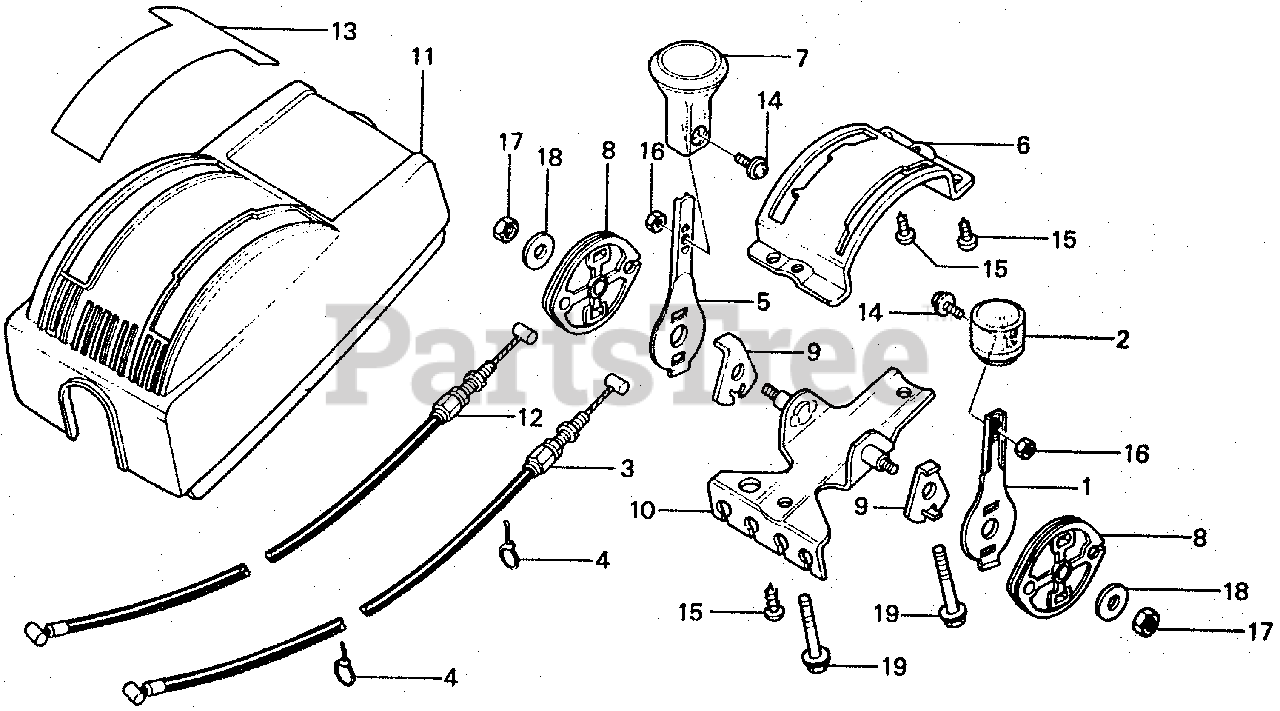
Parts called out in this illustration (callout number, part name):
1	LEVER, THROTTLE
2	KNOB, THROTTLE LEVER
3	CABLE, THROTTLE
4	TIE, CABLE
5	LEVER, CHANGE
6	BASE, CONTROL
7	KNOB, LEVER
8	REEL, CABLE
9	STOPPER, REEL
10	STAY, CABLE
11	COVER, CONTROL
12	CABLE, CHANGE
13	MARK, CONTROL (ENGLISH) (NOT AVAILABLE)
14	SCREW-WASHER (4X8)
15	SCREW, TAPPING (5X12)
16	NUT, HEX. (4MM)
17	NUT, HEX. (6MM)
18	WASHER, PLAIN (6MM)
19	BOLT, FLANGE (6X32)
